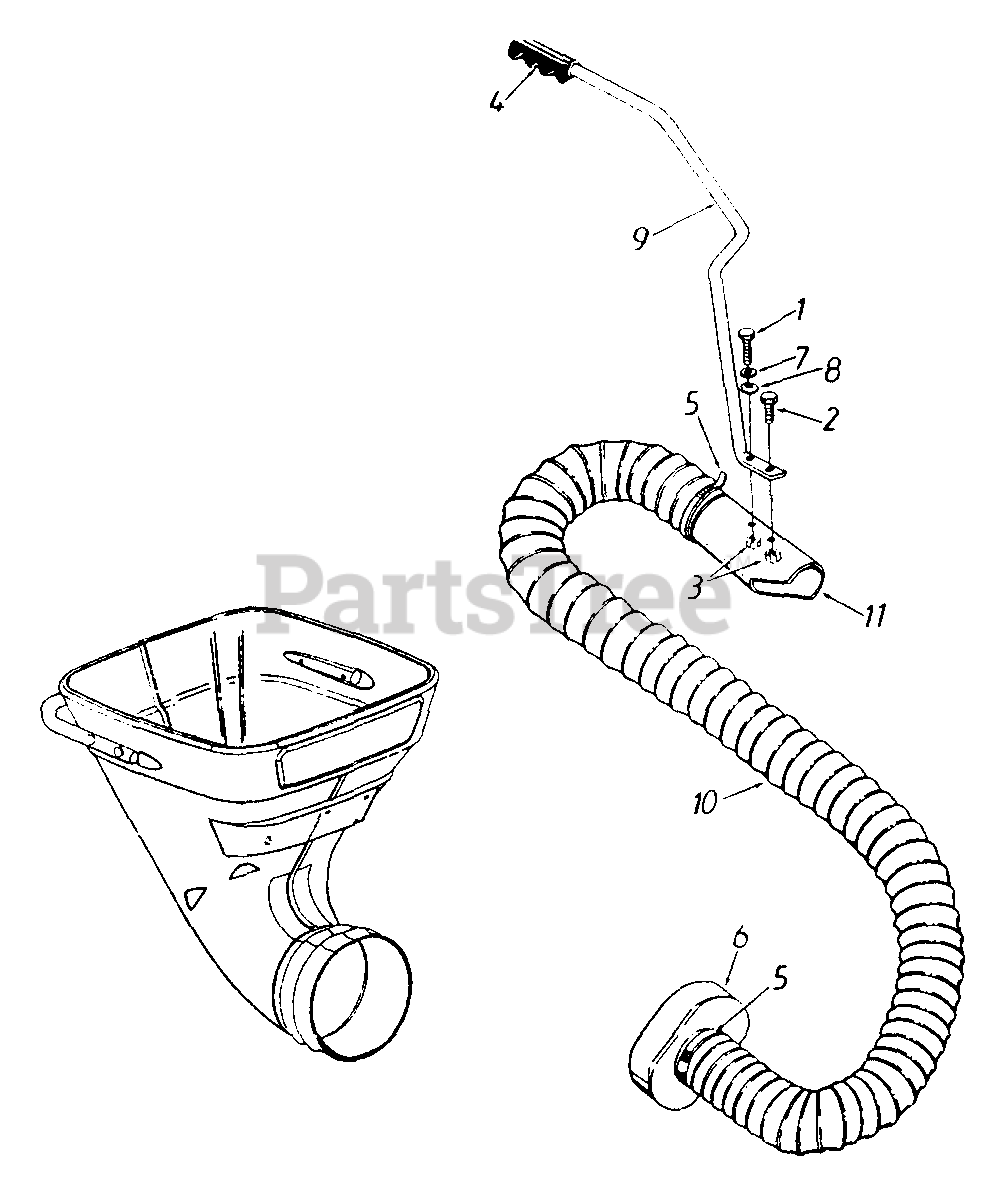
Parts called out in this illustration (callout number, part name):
1	Hex Bolt 1/4-20 x 1.25" Lg.
2	Hex Bolt 1/4-20 x .62" Lg.
3	Hex L-Nut 1/4-20 Thd.
5	Adj. Hose Clamp 5" Dia.
7	Fl-Wash..281" I.D. x .50" O.D. x .06"
8	Saddle Washer .32" I.D. x .937"
10	Hose - 5" Dia.
11	Nozzle Tube
